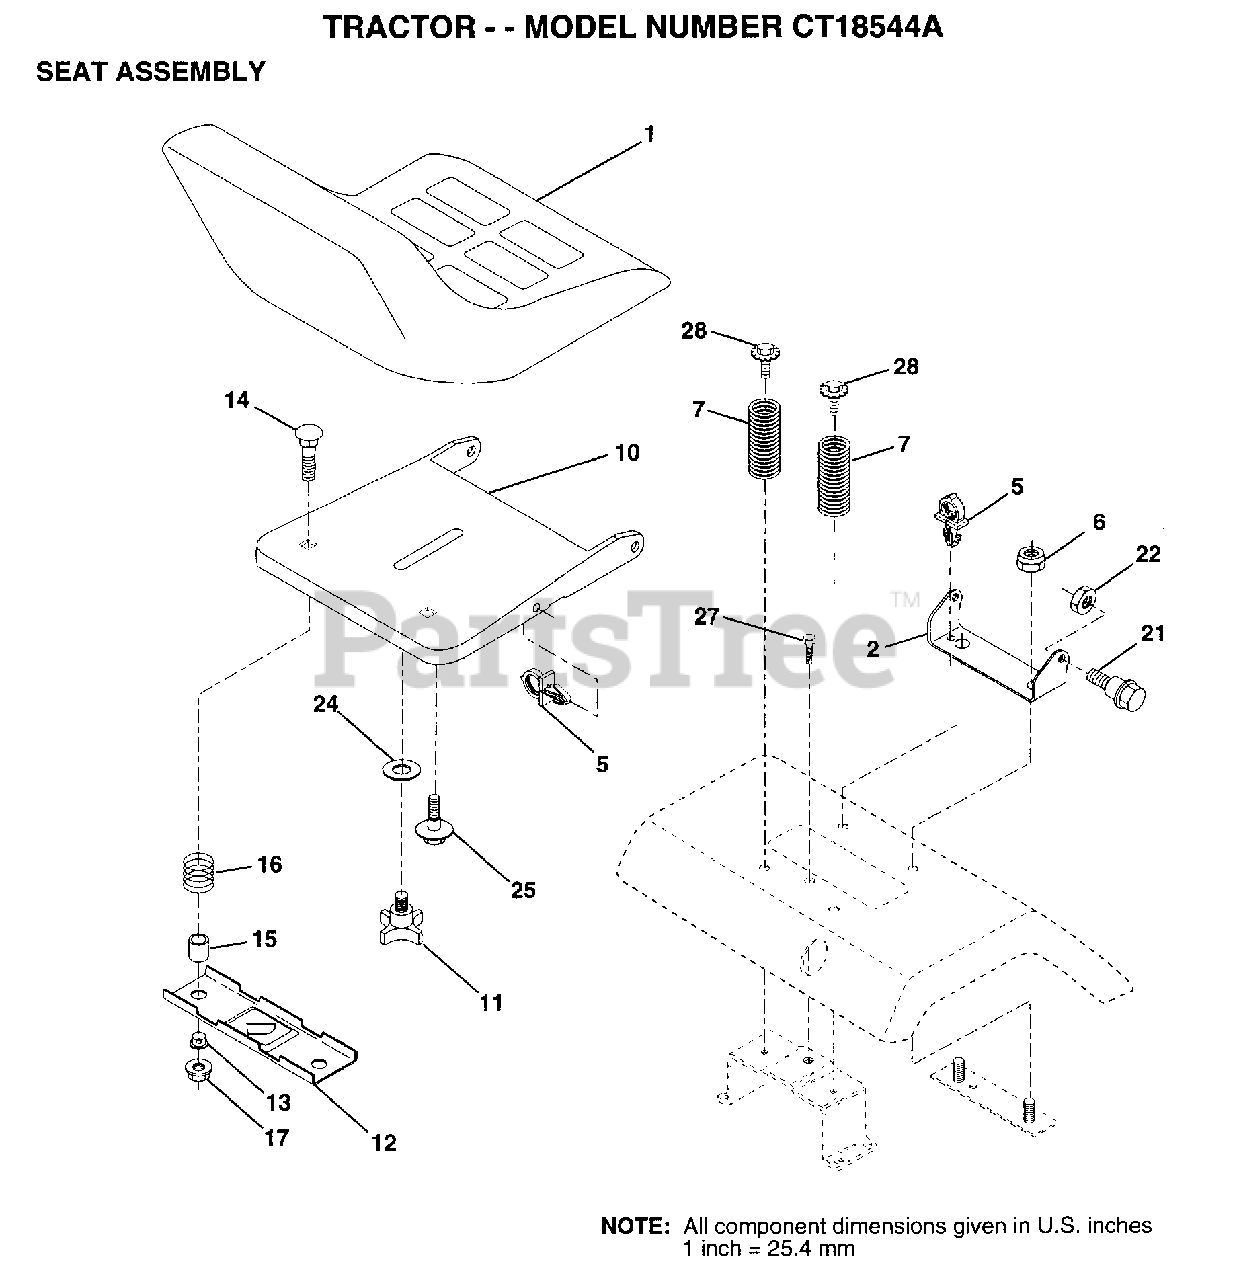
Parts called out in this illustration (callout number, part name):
2	BRACKET PVT SEAT
5	CLIP.PUSH-IN.HING
7	SPRING COMPRESSIO
11	"KNOB 1/2"" YT"
12	BRKT SWITCH
13	BUSHING
15	SPACER SPLIT
16	SPRING COMPRESSED
21	"BOLT,SHOULDER"
24	WASHER
25	"BOLT,SHOULDER"
27	SCREW LT
28	BOLT.5/16-18.UNC
